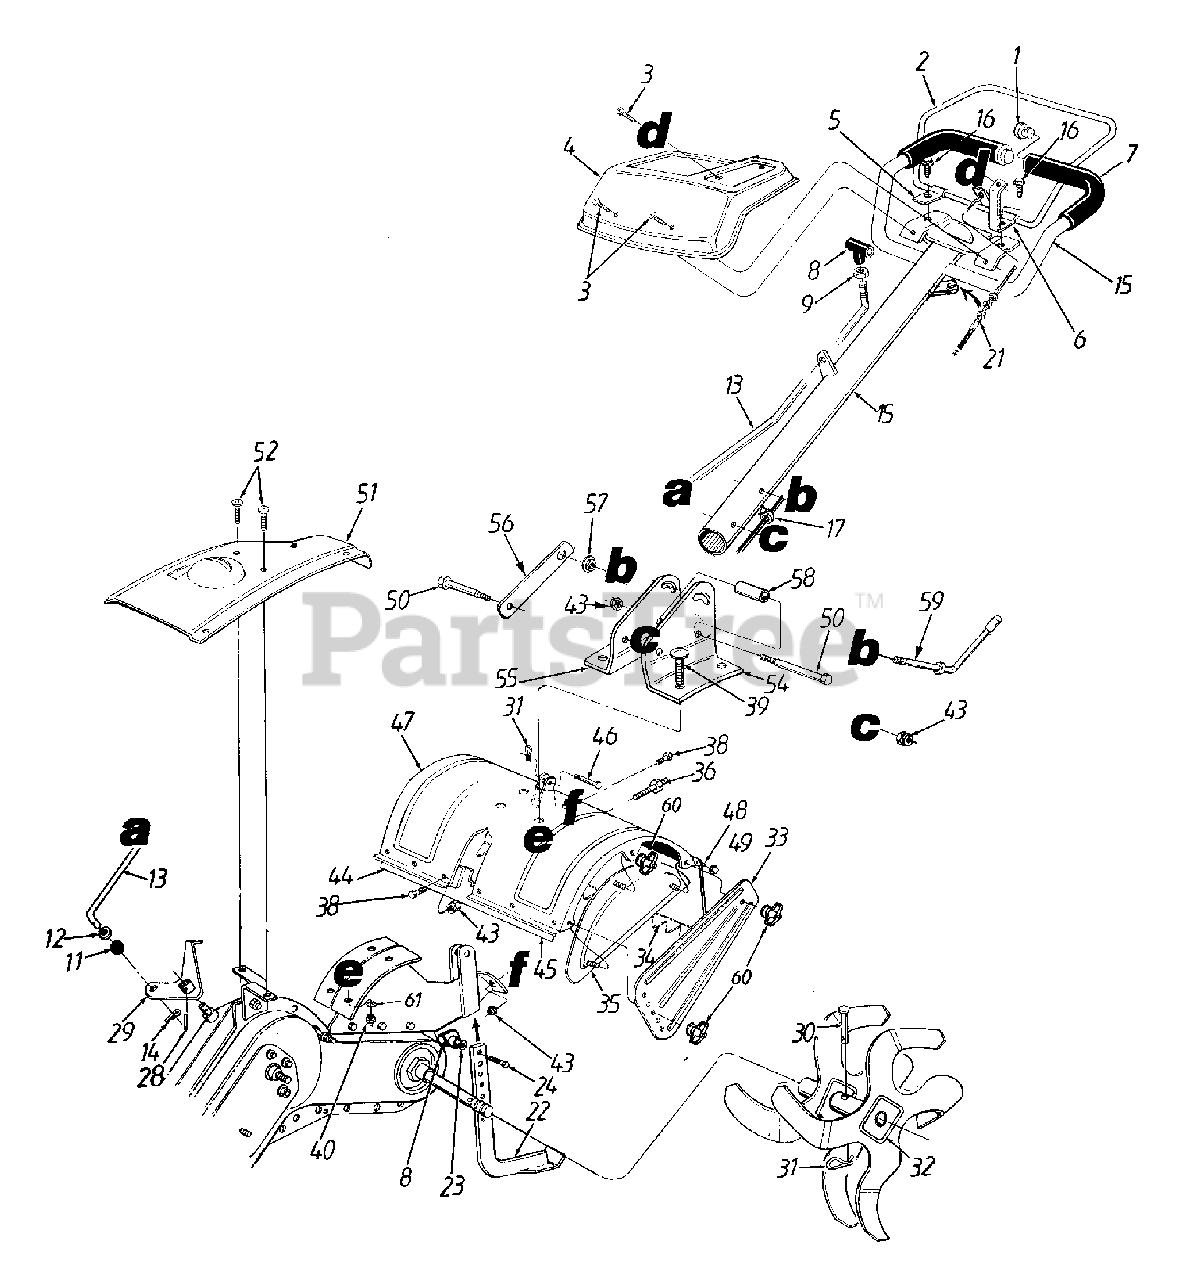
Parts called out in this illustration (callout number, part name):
1	Vinyl End Plug
3	Torx Mach. AB-Tap Scr. 1/4 x .62"
7	Grip
9	Hex Jam Nut 3/8-16 Thd.
11	Rubber Washer
12	Fl-Wash. .344" I.D. x .6" O.D.
13	Gear Shift Rod
14	Hairpin Clip
21	Clutch Cable
23	Fl-Wash. 3/8" I.D. x 5/8" O.D.
24	Hex Bolt 3/8-16 x 1" Lg.*
28	Spiral Pin 3/16" x 1"
36	Hex Cap Bolt 5/16-18 x 1.25" Lg.
38	Hex Bolt 5/16-18 x .75" Lg.
39	Carriage Bolt 3/8-16 x 1" Lg.
40	Hex Ins. L-Nut 3/8-16 Thd.
43	Hex Flange Top L-Nut 5/16-18
46	Clevis Pin .375" Dia.
49	Cap Speed Nut
50	Hex Bolt 5/16-18 x 3" Lg.
52	Torx Mach. AB-Tap Scr. 1/4 x .6"
57	Hex Flange Nut 3/8-24 Thd.
58	Spacer .322 Dia.
59	Handle Adjustment Crank
60	Knob 5/16-18 Thd.
61	L-Washer 3/8" I.D.
